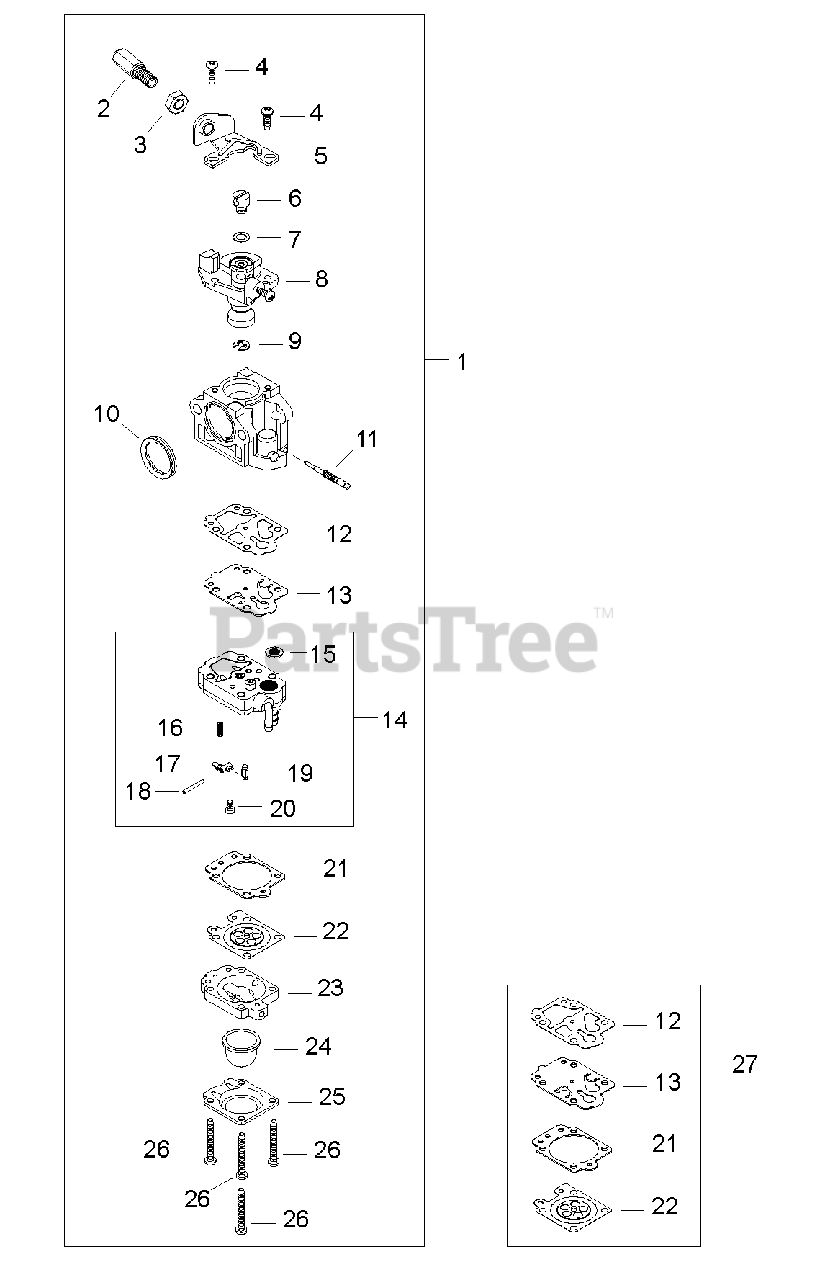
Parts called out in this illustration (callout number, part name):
1	CARBURETOR - WYK-297
2	ADJUSTER, THROTTLE CABLE
3	NUT, ADJUSTER LOCK M7
4	SCREW
5	BRACKET, THROTTLE CABLE
6	SWIVEL
7	WASHER
8	VALVE ASSY, THROTTLE
9	E-RING
10	RING, PACKING
11	NEEDLE, HIGH SPEED
12	GASKET, PUMP
13	DIAPHRAGM, PUMP
14	BODY ASSY, PUMP
15	SCREEN, FUEL INLET
16	SPRING, METERING LEVER
17	LEVER, METERING
18	PIN, METERING LEVER
19	VALVE, INLET NEEDLE
20	SCREW
21	GASKET, METERING DIAPHRAGM
22	DIAPHRAGM, METERING
23	BODY ASSY, PURGE
24	BULB, PURGE
25	RETAINER, PURGE BULB
26	SCREW
27	GASKET / DIAPHRAGM KIT
